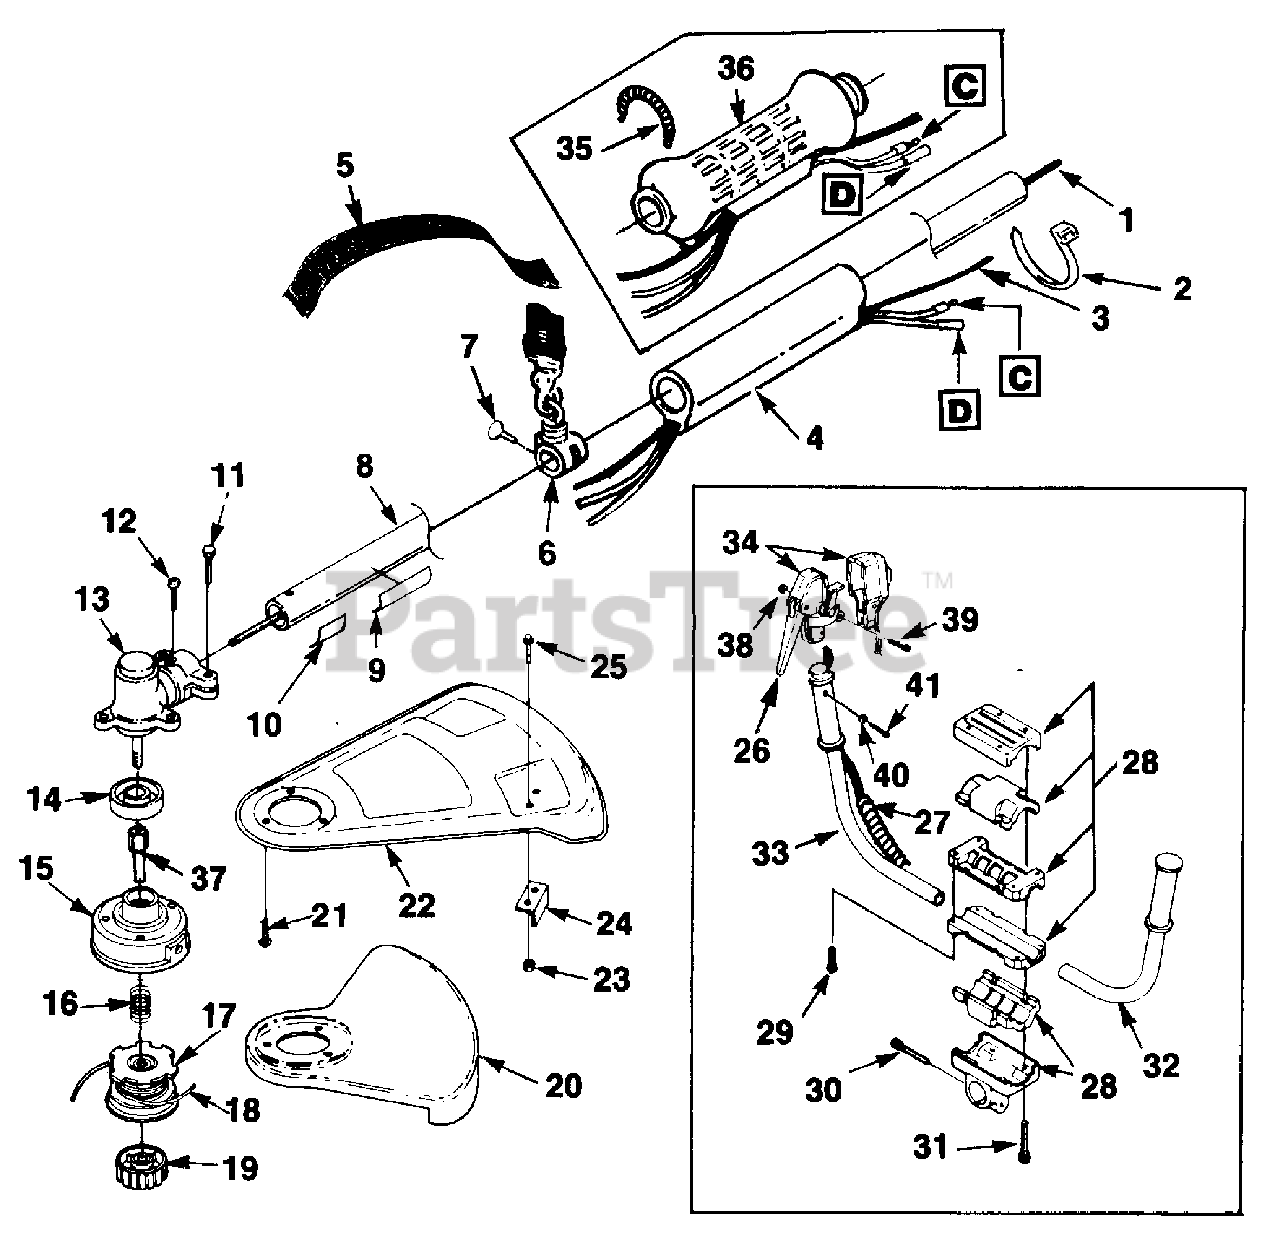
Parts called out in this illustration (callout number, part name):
1	DRIVE SHAFT
2	CABLE- Tie
3	THROTTLE CABLE
4	GRIP- Handle
5	HARNESS (w/Connector)
6	BRACKET- Hanger
7	SCREW (10-24 x 1/2")
8	HOUSING- Drive shaft
9	DECAL- Starting instr.
10	DECAL- Warning
11	SCREW (10-24 x 1")
12	SCREW (10-24 x 1/2")
13	GEARHEAD ASSY.
14	WASHER- Flange
15	HOUSING & EYELET
16	SPRING- Compression
17	SPOOL & STRING (Dual Line)
18	LINE- Replacement (.095 Dia.)
19	RETAINER
20	GUARD- Blade
21	SCREW (10-24 x 1/2")
22	GRASS DEFLECTOR
23	NUT (10-24)
24	BLADE- Cut off
25	SCREW (10-24 x 3/8")
26	THROTTLE
27	SLEEVE- Plastic
28	BRACKET- Handle bar
29	SCREW- Soc. hd.
30	SCREW- Hex hd.
31	SCREW- Hex hd.
32	HANDLE BAR
33	HANDLE BAR & GRIP
34	SWITCH & LEAD
35	SPRING- Torsion
36	GRIP- Handle
37	CONNECTOR- Drive
38	NUT (4 M)
39	SCREW (4 M)
40	WASHER- Lock
41	SCREW- Thd. Forming
